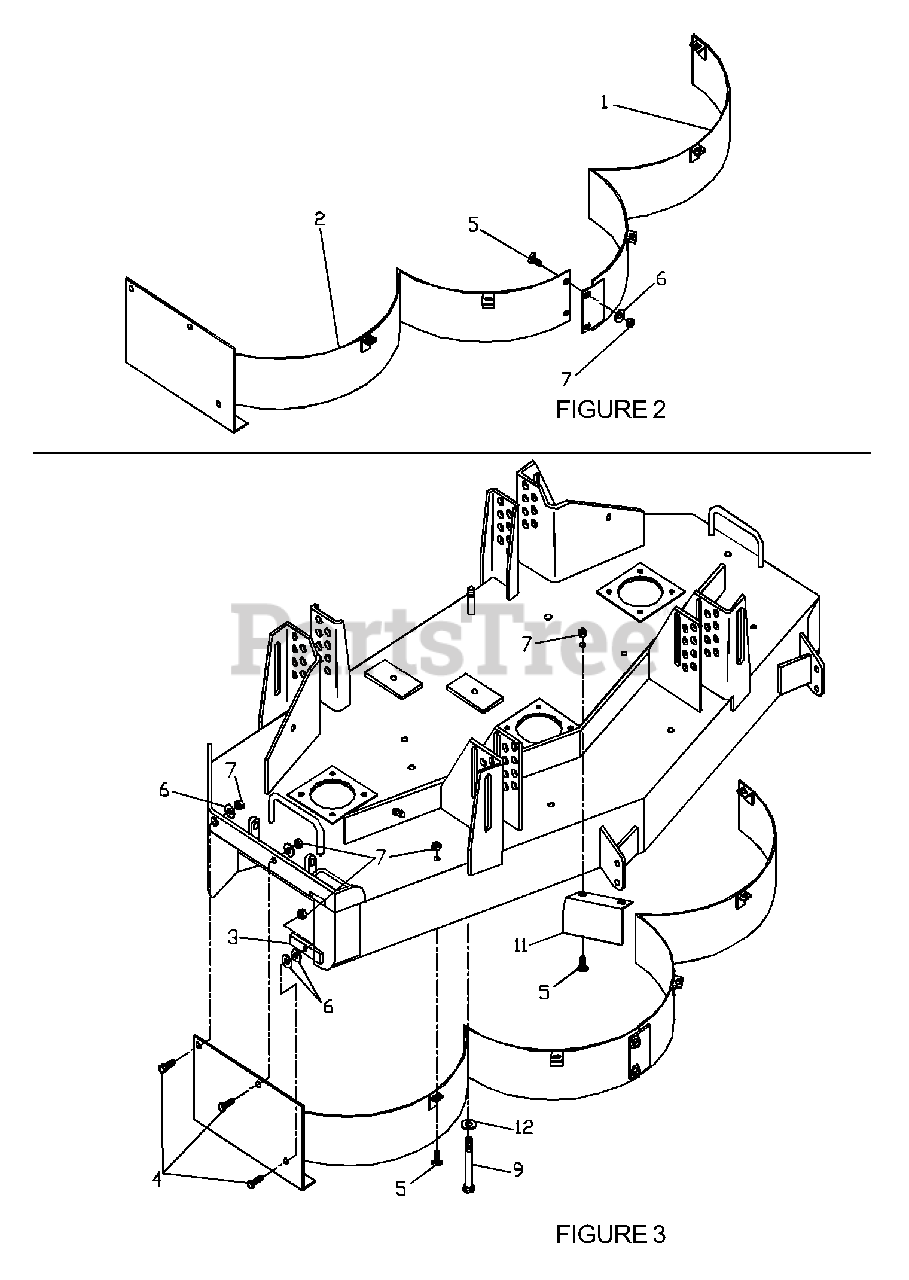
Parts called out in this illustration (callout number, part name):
1	BAFFLE, 48"
2	DISCHARGE BAFFLE, 48"
4	HCS 5/16C X 1" GRADE 5
5	5/16C X 5/8" CARRIAGE BOLT
6	5/16 FLAT WASHER
7	5/16C CENTERLOCK NUT
8	MULCH BLADE 16 1/4"
9	HCS 5/16C X 4 1/2"
11	CENTER DEFLECTOR
12	FLANGED WASHER
